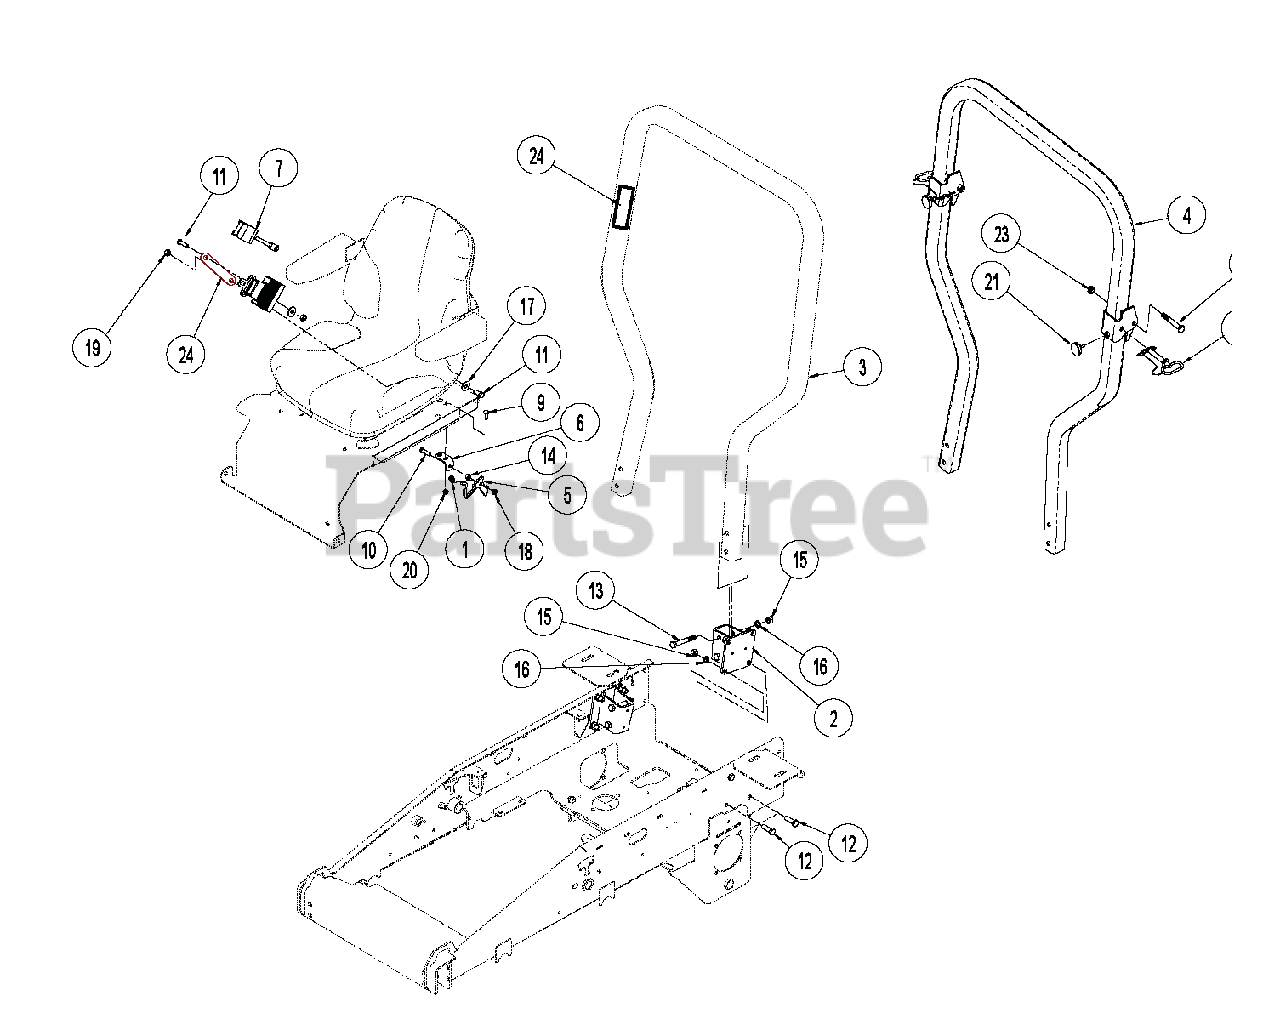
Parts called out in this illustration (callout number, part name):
1	SPRING, COM .600X.056X.875 Y
2	WLDT, ROPS MOUNT
3	ROPS, FEMCO FIXED HORNET
4	ROPS, FEMCO FOLDABLE HORNET
5	LATCH, HOOK
6	BRACKET, LATCH
7	ASSY, SEAT BELT
8	ASSY, ROPS LOCK PIN S/O
9	BOLT, 5/16-18X1.00 CRG 2 Y
10	BOLT, 3/8-16X1.25 HEX 5 Y
11	BOLT, 7/16-14X1.00 HEX 5 Y
12	BOLT, 1/2-13X1.50 HEX 5 Y
13	BOLT, 1/2-13X3.50 HEX 5 Y
14	NUT, 3/8-16 STD HEX GR5 Y
15	NUT, 1/2-13 STD HEX GR5 Y
16	WASHER, .500 MED SPRG LOCK Y
17	WASHER, .438 REG FLAT Y
18	LOCKNUT, 3/8-16 CROWN Y
19	LOCKNUT, 7/16-14 CROWN Y
20	LOCKNUT, 5/16-18 WHIZ Y
21	KNOB, ROUND 5/16-18 X .750
22	BOLT, 1/2-13X3.25 HEX 5 Y
23	LOCKNUT, 1/2-13 CENTER Y
24	DECAL, FEMCO ROPS DANGER
